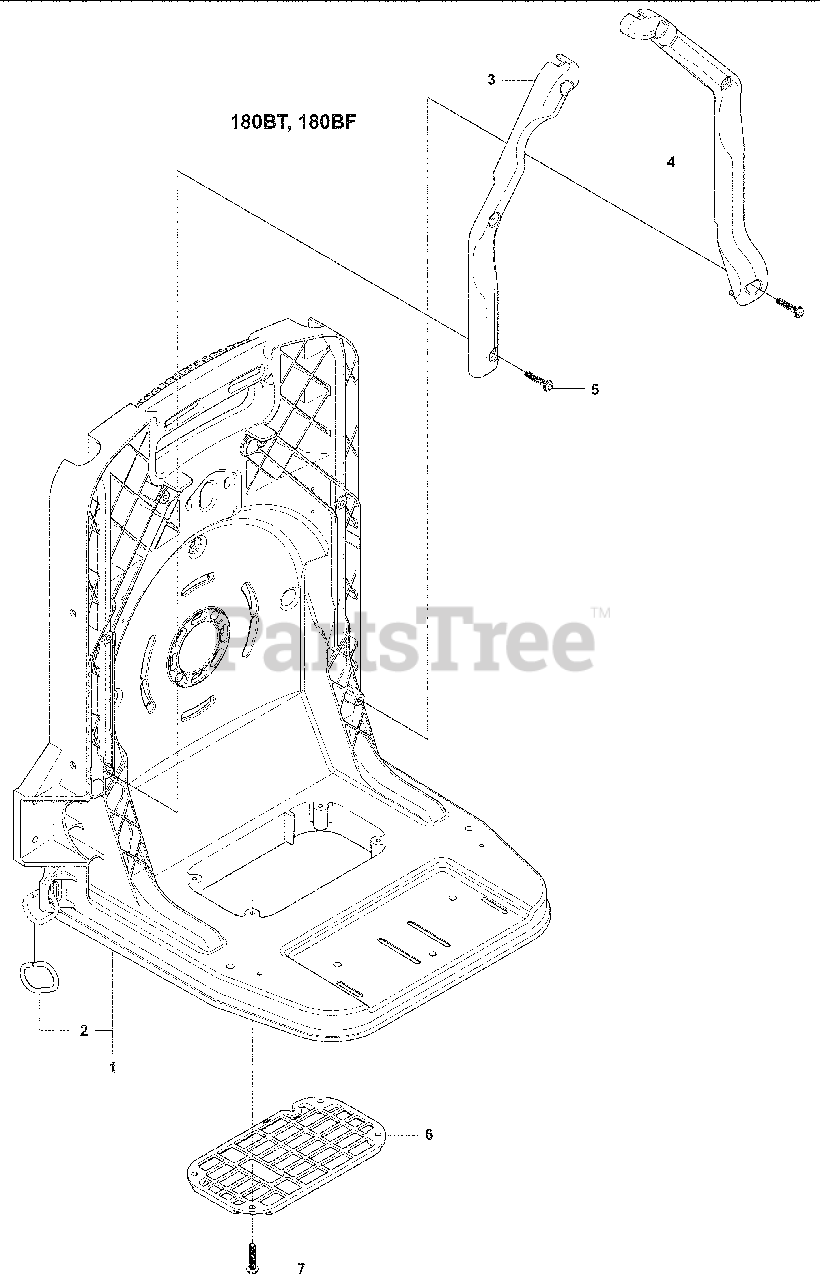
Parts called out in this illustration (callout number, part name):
2	Ring
5	Screw
7	Screw
